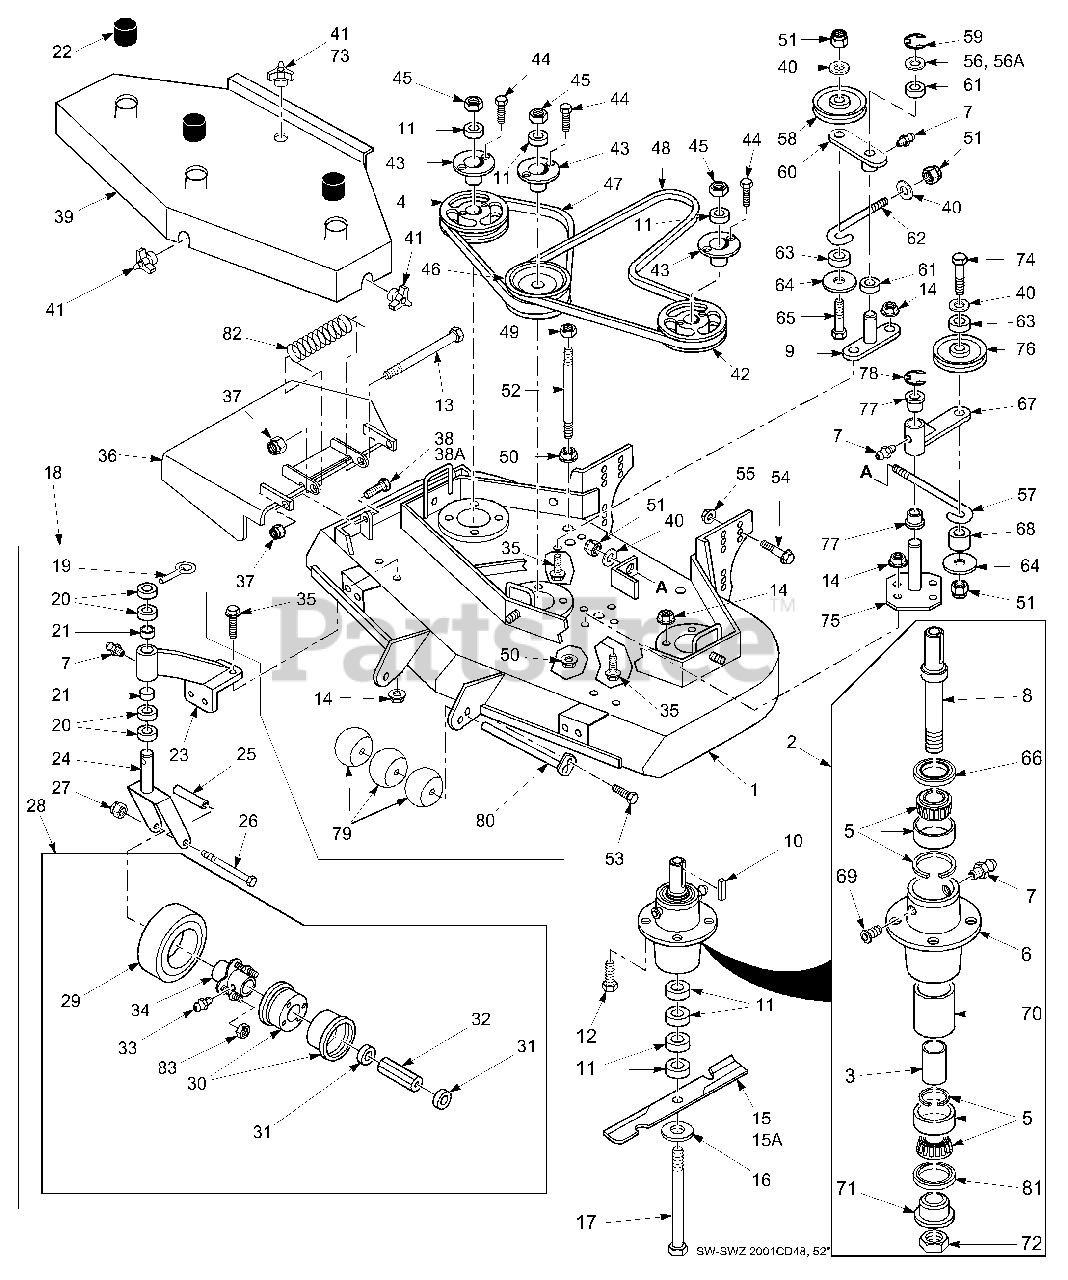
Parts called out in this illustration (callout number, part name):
1	Cutter Deck Adv.
2	Spindle Assembly
3	Spacer, Inside
4	Pulley
5	Tapered Bearing (Two)
6	Spindle Housing
7	Grease Fitting Str. 5/16
8	Spindle Shaft, Tapered Brng
9	Idler Pivot
10	Key, 1/4 x 1/4 x 2"
11	Spacer, Cutter Blade - Small
12	Bolt, 5/16-18 x 1-1/4" Hex Head
13	Bolt, 5/16-18 x 4-1/4" Hex Head
14	Serrated Flange Nut, 5/16-18
15	Cutter Blade 18"
15A	Cutter Blade 18 Hi Lift
16	Flatwasher, 5/8" (.688 x 1.75 x .134)
17	Hex Head Bolt, 5/8-11 x 9-1/2"
18	Caster Assembly,
19	Quick Pin
20	Spacer, Caster Yoke, 1/2" thick
21	Bronze Bearing
22	Spindle Shield
23	Support Assembly,
24	Caster Yoke
25	Sleeve, Caster Wheel Bearing
26	Hex Hd Bolt, 1/2-13 x 5-1/2"
27	Elastic Stop Nut, 1/2-13
28	Wheel Assy.
29	Tire only, Caster Wheel
30	Rim Pair, Caster Wheel
31	Bearing Retainer, Caster Wheel
32	Roller Bearing, Caster Wheel
33	Grease Fitting 45 deg., 1/4-28
34	Hub Assembly,
35	Capscrew, 5/16-18 x 3/4"
36	Discharge Chute
37	Nut, 5/16-18 Elastic Elastic Stop
38	Bolt, 5/16-18 x 1" Hex Head
39	Belt Cover
40	Flat Washer, 3/8" Special
41	Wing Nut, 3/8-16 (Large)
42	Pulley
43	Tapered Hub
44	Bolt, 1/4-20 x 3/4" Hex Head
45	Nut, 5/8-11 Hex
46	Pulley, Double
47	Belt, RH Blade Drive
48	Belt, Blade Drive
49	Nut, 3/8-16, Nut Centerlock
50	Nut, 3/8-16, Serrated Flange
51	Nut, 3/8-16 Elastic Stop
52	Support, Belt Cover
53	Bolt, 5/16-18 x 1/2" Hex Head
54	Cpscrw,7/16-14 x 1" Ser Flng H Hd
55	Nut, 7/16-14 Serrated Flange
56	Flat Washer 3/4" Special
56A	Flat Washer 3/4" Special
57	J-Hook
58	Idler Pulley, "V" Groove
59	Retaining Ring, 3/4" Ext."E"
60	Idler Arm Assy.
61	Bronze Bearing
62	J-Rod, Idler Pulley
63	Spacer, J-Rod
64	Washer, 3/8 x 1-1/2 x 16 ga.
65	Bolt, 3/8-16 x 2-1/4" Hex Head
66	Seal, Cutter Spindle
67	Idler Arm Assy
68	Spacer, J-Rod
69	Relief Fitting, Cutter Spindle
70	Spacer, Outside, Cutter Spindle
71	Spindle Bushing
72	Nut, Cutter Spindle
73	Wing Nut, 3/8-16 (Small) Top Side
74	Bolt, 3/8-16 x 3-1/2" Hex Head
75	Idler Pivot
76	Idler Pulley, Belt Clutch
77	Bronze Bearing
78	Retaining Ring
79	Guide Roller
80	Roller Shaft
81	Seal, Cutter Spindle
82	Spring, Chute Return
83	Nut, 3/8-24 Tapered
